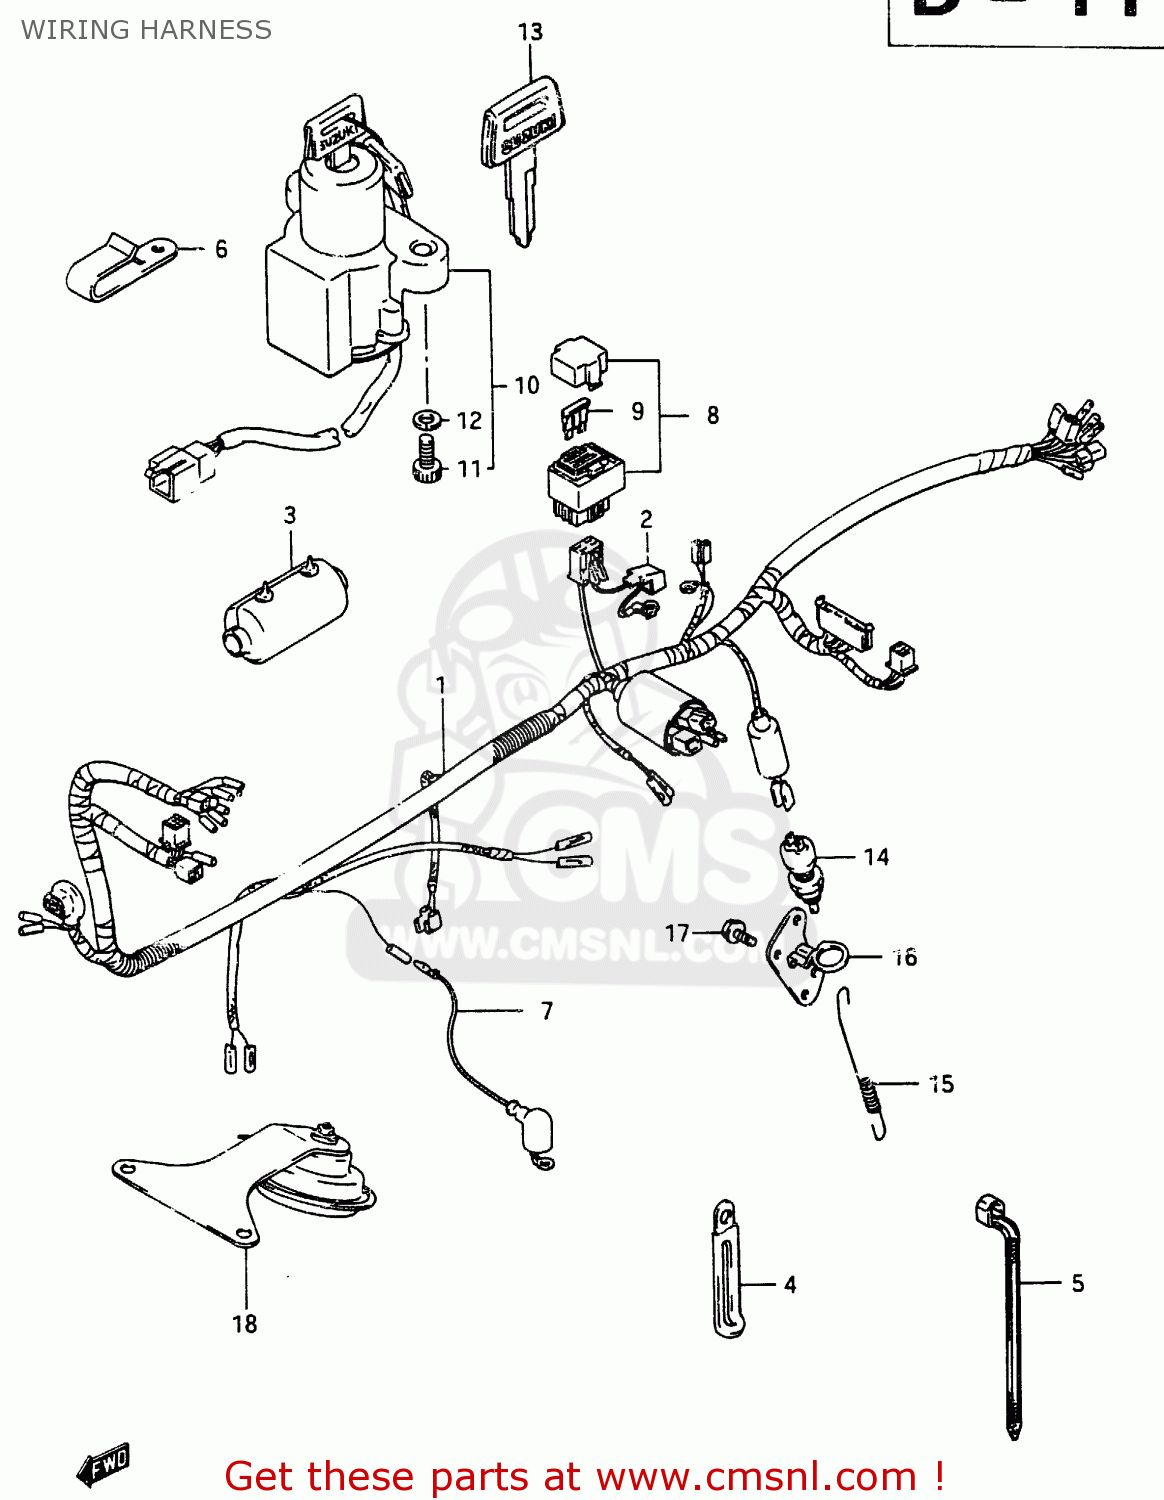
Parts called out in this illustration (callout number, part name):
1	HARNESS, WIRING
2	CAP, BATTERY (+) TERMINAL
3	BOOT,WIRING HARNESS
4	CLAMP
5	CLAMP(L:95)
6	CLAMP,HANDLE SWITCH
7	WIRE,WATER TEMPERATURE GAUGE
8	BOX ASSEMBLY,FUSE
9	FUSE(20A)
10	LOCK ASSY
11	BOLT
12	WASHER,LOCK
13	KEY,BLANK
14	SWITCH ASSY,STOP LAMP
15	SPRING
16	PLATE, STOP LAMP SWITCH
17	BOLT
18	HORN ASSY
